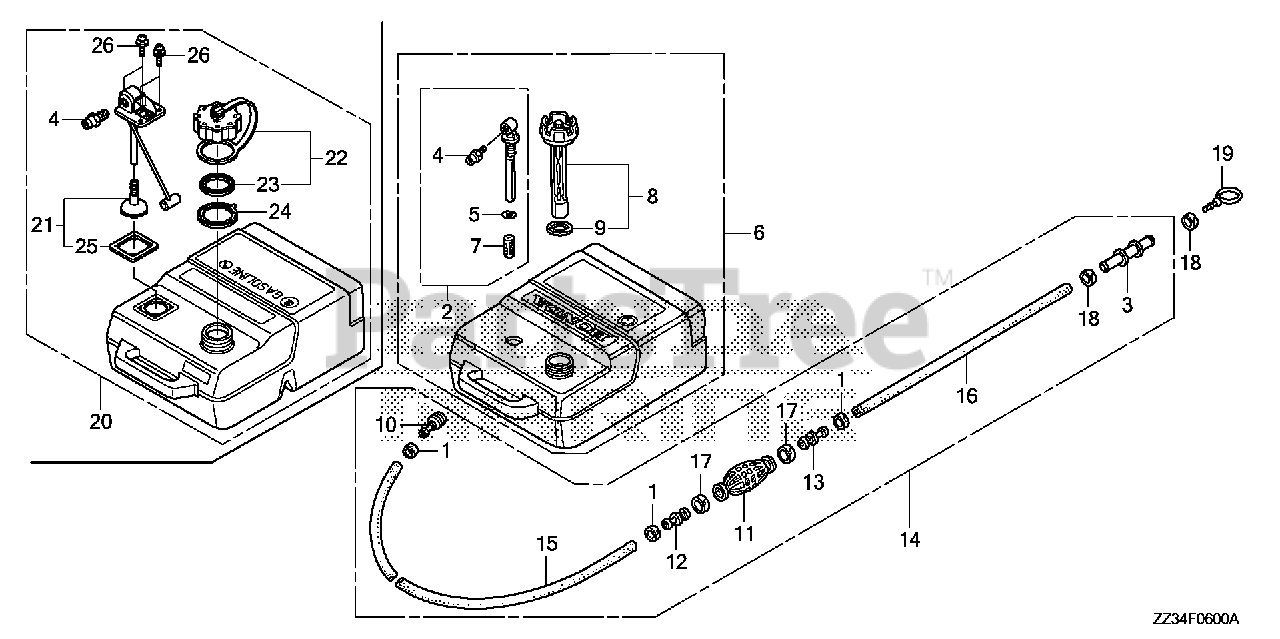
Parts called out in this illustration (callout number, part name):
1	CLAMP, FUEL TUBE
1	CLAMP, FUEL TUBE (14.0)
2	JOINT ASSY., FUEL
3	JOINT, FUEL TUBE
4	FITTING, QUICK DISCONNECT
5	O-RING
6	TANK ASSY., FUEL
7	FILTER, FUEL
8	CAP, FUEL FILLER
9	GASKET, FUEL CAP
10	CONNECTOR, FUEL
11	BULB, PRIMER
12	VALVE, IN.
13	VALVE, OUTLET
14	TUBE ASSY., FUEL TANK (CONNECTOR TYPE)
15	TUBE, FUEL LONG (7.3X2000)
16	TUBE, FUEL SHORT (7.3X500)
16	TUBE, FUEL SHORT
17	BAND, TUBE CLIP (20MM)
18	BAND, TUBE CLIP (12.5MM)
19	PLUG, FUEL TUBE
20	TANK ASSY., FUEL
21	FILTER KIT, FUEL
22	CAP, FUEL FILLER
23	GASKET, FUEL CAP
24	RETAINER, PRESSURE RELIEF
25	GASKET, FUEL PICK-UP
26	BOLT-WASHER (5MM) (SEAL)
